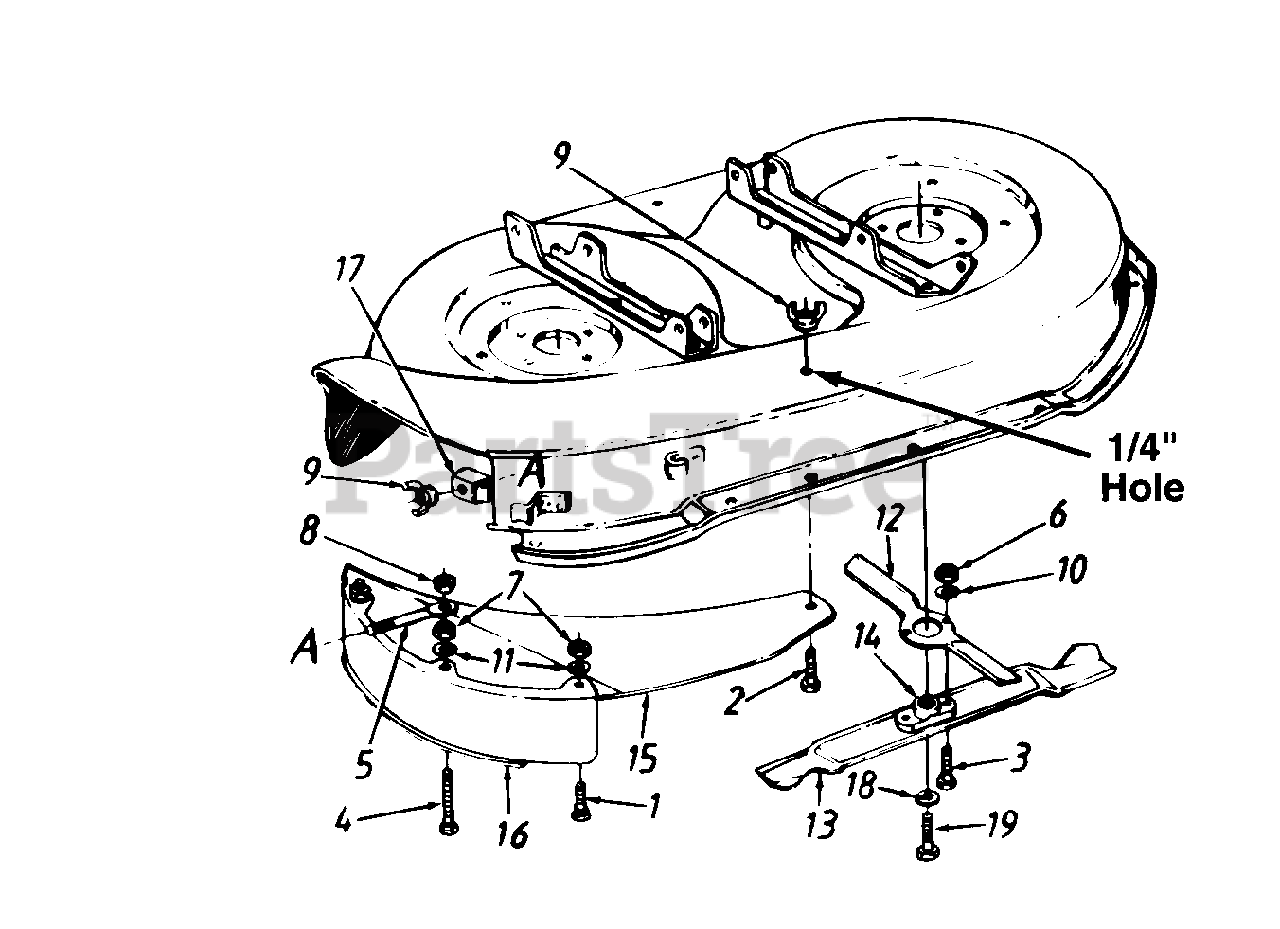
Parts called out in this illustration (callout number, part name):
1	Carriage Bolt 1/4-20 x .62" Lg.
2	Hex Bolt 1/4-20 x .62" Lg.
3	Hex Bolt 7/16-20 x 1.25" Lg. (Gr. 5)
4	Carriage Bolt 1/4-20 x 1" Lg.
5	Retaining Bolt
6	Hex Nut 7/16-20 Thd.
7	Hex Nut 1/4-20 Thd.
8	Hex L-Nut 1/4-20 Thd.
9	Wing Nut
10	L-Wash. 7/16" I.D.
11	L-Wash. 1/4" I.D.
12	Mulching Blade 12.5"
13	Mulching Blade 19.38"
14	Blade Adapter
18	L-Wash. 3/8" I.D.
19	Hex Bolt 3/8-24 x 1" Lg. (Gr. 8)
